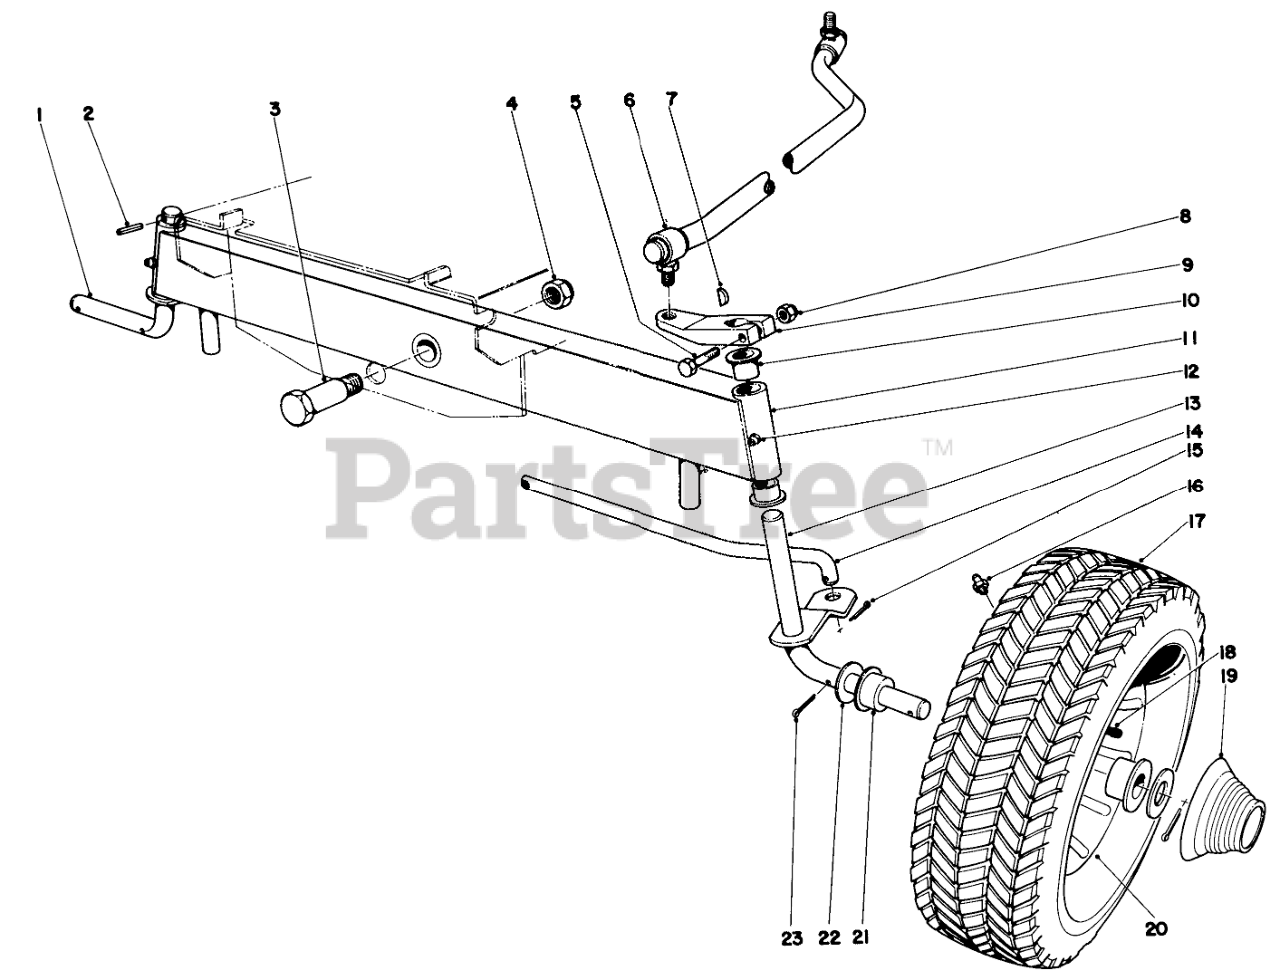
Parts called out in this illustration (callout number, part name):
1	Spindle R.H. 905
2	PIN-SPRING
3	Shoulder Bolt
5	SCREW-HH
6	Steering Rod
7	KEY-WOODRUFF
9	Arm Steering
10	BUSHING-FLANGE
11	Front Axle
12	GREASE FITTING
13	Spindle L.H. 905
14	Tie Rod
15	PIN-COTTER
16	FITTING-GREASE
17	Wheel
18	Valve Stem
19	FRONT HUB CAP
21	Bushing
22	WASHER-FLAT
23	PIN-COTTER
